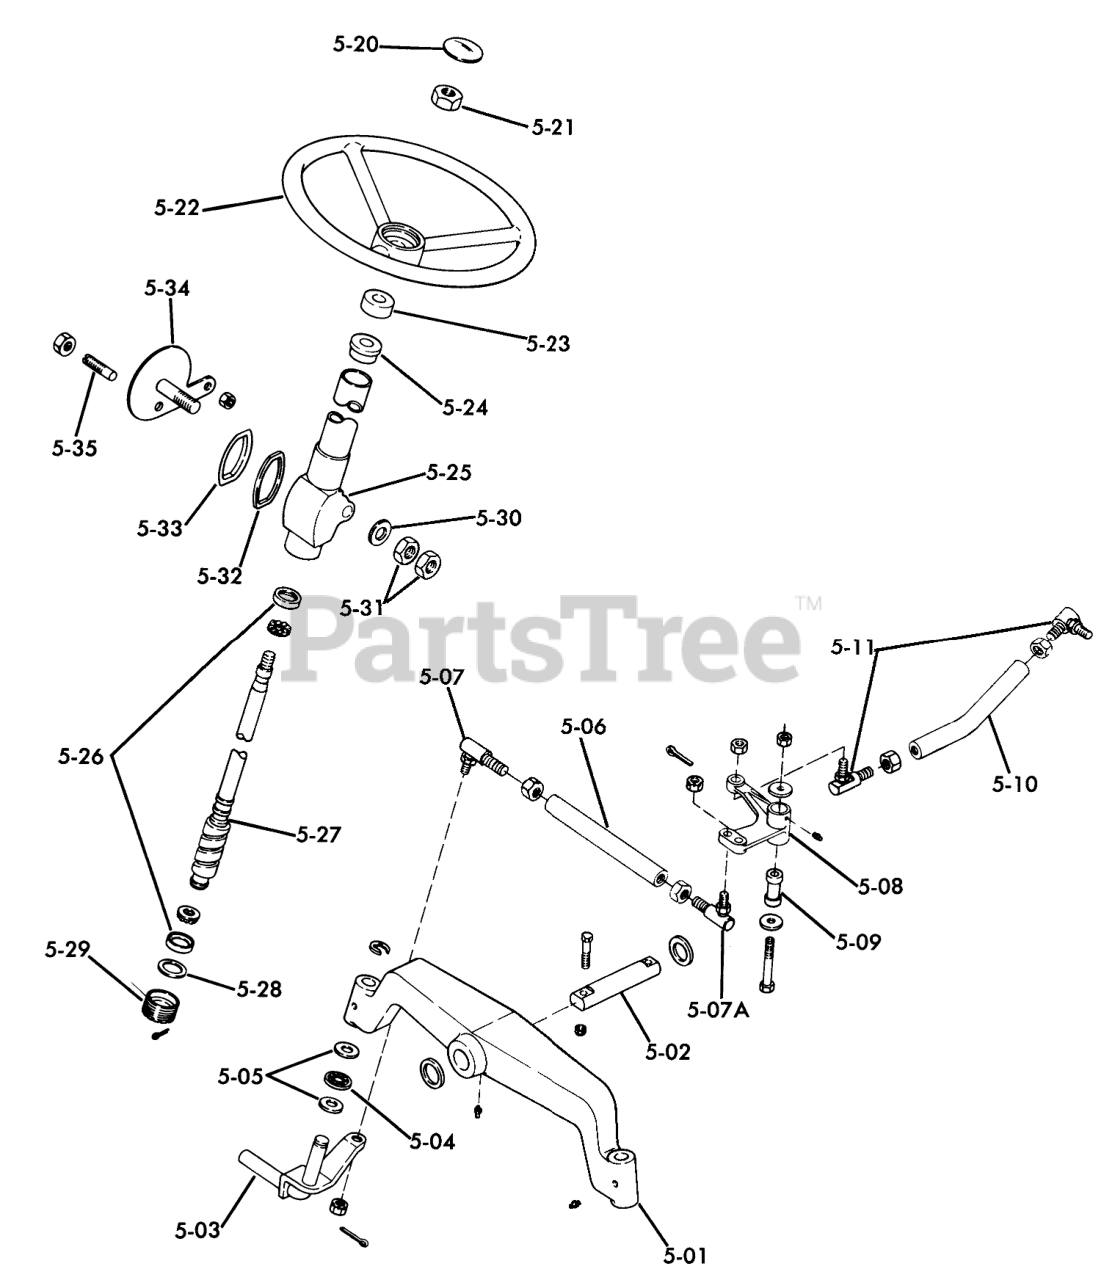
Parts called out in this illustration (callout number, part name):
5-01	FITTING-GREASE
5-03	E RING
5-05	WASHER-THRUST
5-25	Fitting-Grease
5-29	Cotter Pin
5-30	Washer 49/64 X 1 1/4
